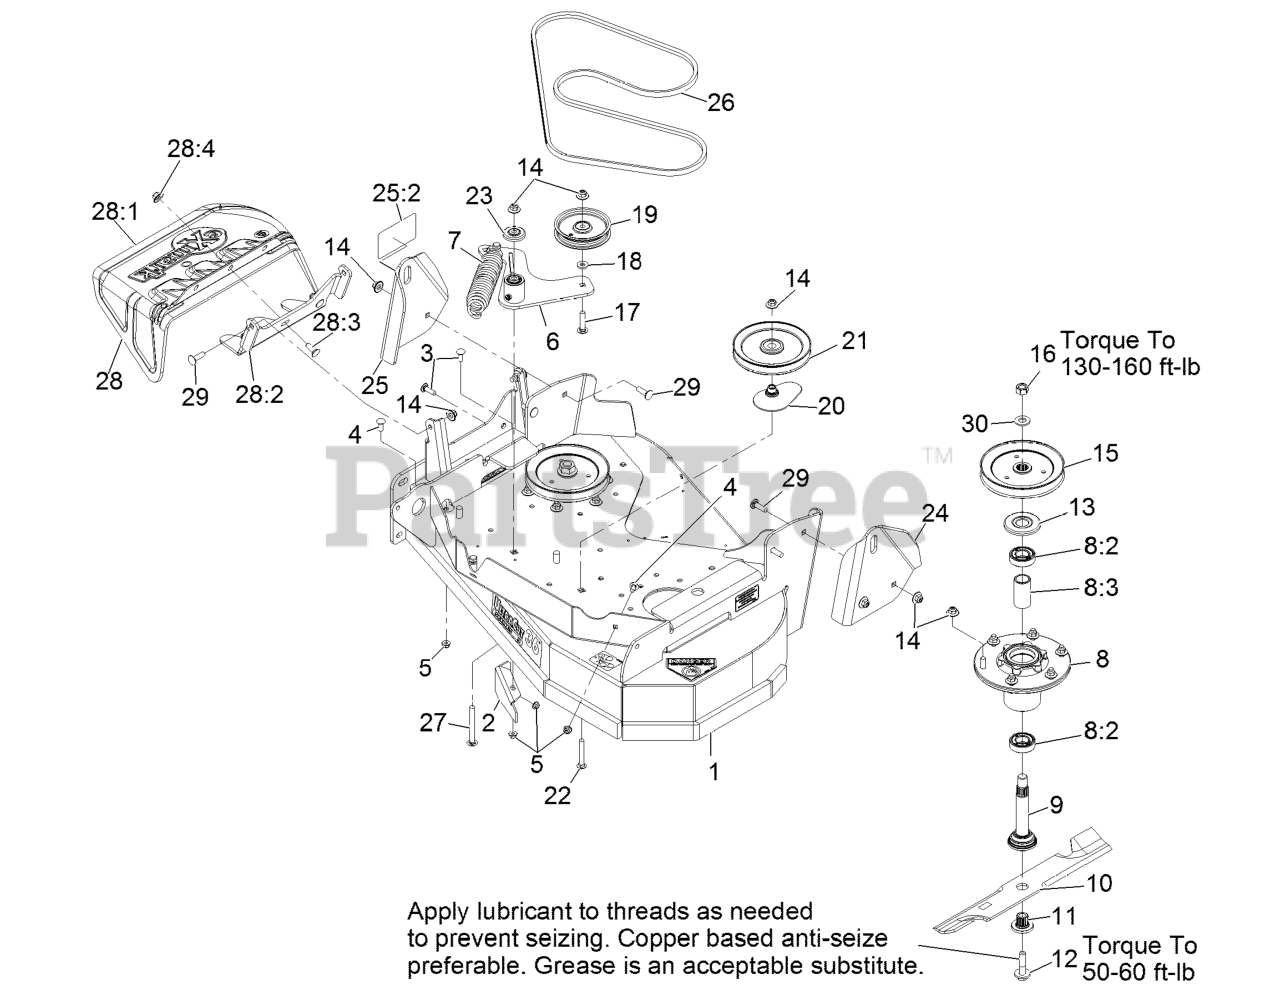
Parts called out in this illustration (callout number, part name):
1	DECK ASM - 36
2	BAFFLE-DOGLEG
3	SCREW-CARR
4	SCREW-CARR
5	NUT-HF, NI
6	IDLER ARM ASM -
7	SPRING-EXTENSION
8	ASM-CUTTER HSG WITH BEARINGS
8:2	BEARING-BALL
8:3	SPACER-BEARING
9	ASM-SPINDLE AND SEAL
11	BUSHING,SPLINED
12	SCREW,SEMS 1/2-20 X 2.19
13	GUARD,BEARING TOP .989
14	Nut-Nyloc 3/8-16 Flg
15	SHEAVE,BLADE DRIVE 6.50
16	NUT-HEX
17	SCREW-CARR
19	PULLEY-IDLER
20	SPACER-PULLEY
21	PULLEY-IDLER
22	SCREW-CARR
23	GUARD-TOP
24	PUSH-TOWER,LH 36
25	PUSH TOWER-RH 36, W/DECAL
25:2	DECAL-WARNING, DISCHARGE
26	BELT-V
27	BOLT-SHOULDER, CARRIAGE 3/8-16 X 3 1/2
28	CHUTE - DISCHARGE ASM
28:1	CHUTE,DISCHARGE
28:2	BRACKET-CHUTE, DISCHARGE
28:3	SCREW-CARR
28:4	Nut-Nyloc 3/8-16 Flg
29	Bolt-Carriage 3/8-16 X 1 1/4
